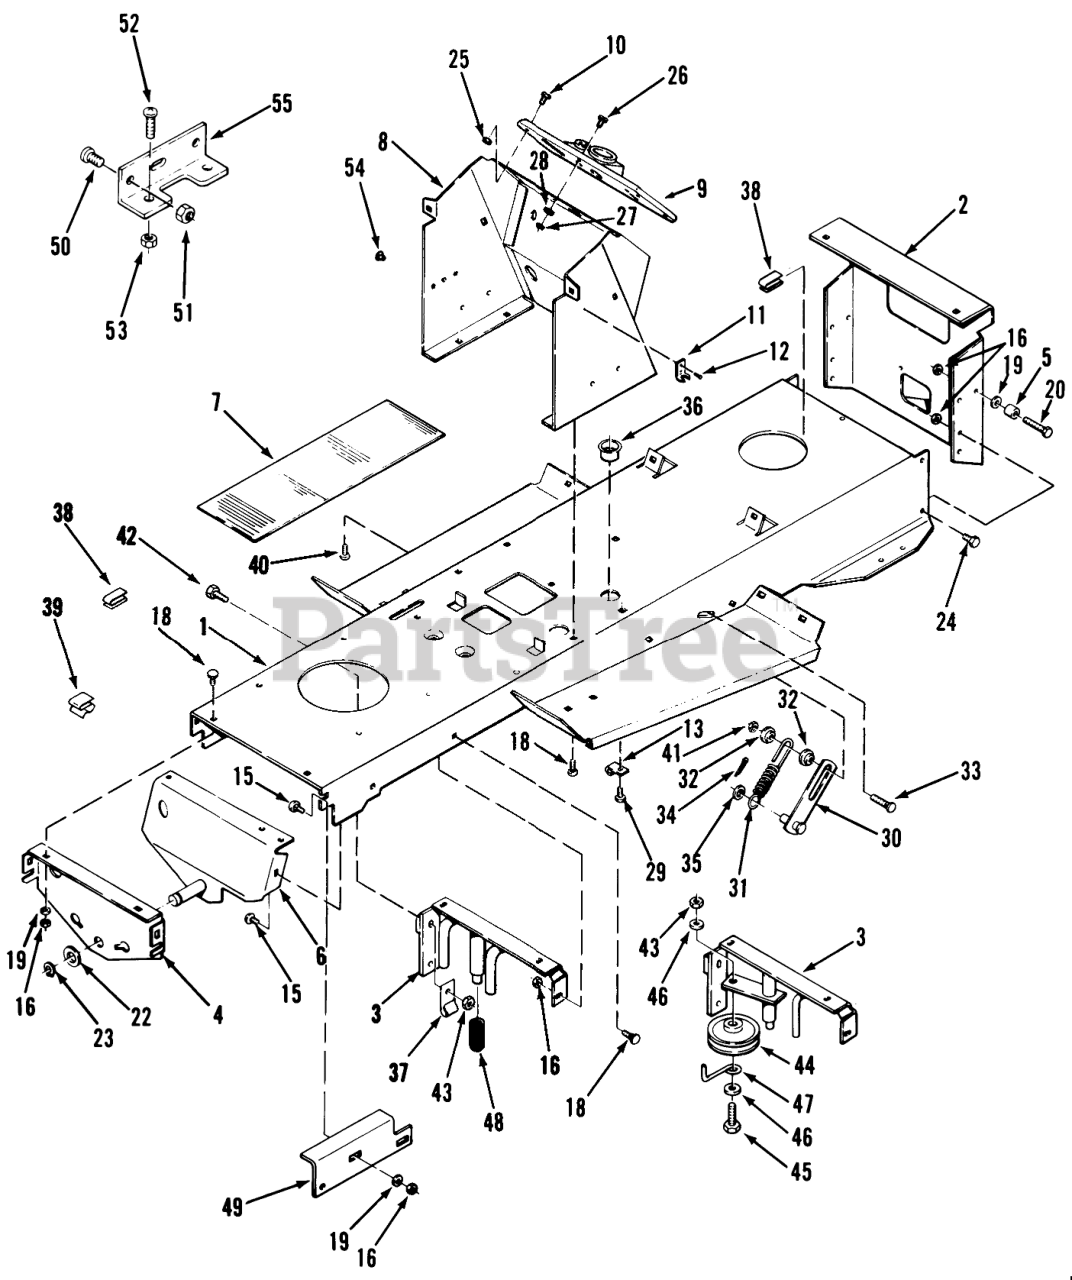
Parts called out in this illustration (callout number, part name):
1	Frame
2	PLATE-DRAWBAR R
3	ASS'Y-FRAME SUPPO R
4	PLATE SUPT - AXLE R
5	BEARING-CAM ROLLER
6	ASS'Y-AXLE SPT RE R
7	PAD-FOOTREST
8	Hoodstand
9	CONSOLE
10	SCREW #10X.62 PHCR
11	Latch Keeper
12	RIVET
13	J-CLIP
15	Bolt-Carriage
16	Nut
18	Bolt
19	WASHER 5/16 SAE
20	Bolt
21	Washer-Lock
22	WASHER
23	Snap Ring
24	Bolt
25	Nut
26	Screw
27	Nut
28	Washer
29	Bolt
30	ASSY LINK B
31	SPRING
32	BUSHING
33	Bolt-Carriage
35	WASHER
36	BUSHING-NYLON 1.093
37	CLIP
38	RETAINER
39	CLIP-CABLE
40	Bolt
41	Nut
42	Bolt
43	NUT
44	IDLER PULLEY R
45	Bolt
46	Washer
47	RETAINER BELT R
49	BRACKET R.H. R
50	Screw
51	Nut
52	Screw
53	Nut
54	PLUG-NYLON .250
55	BRKT-FUSE HOLDER B
